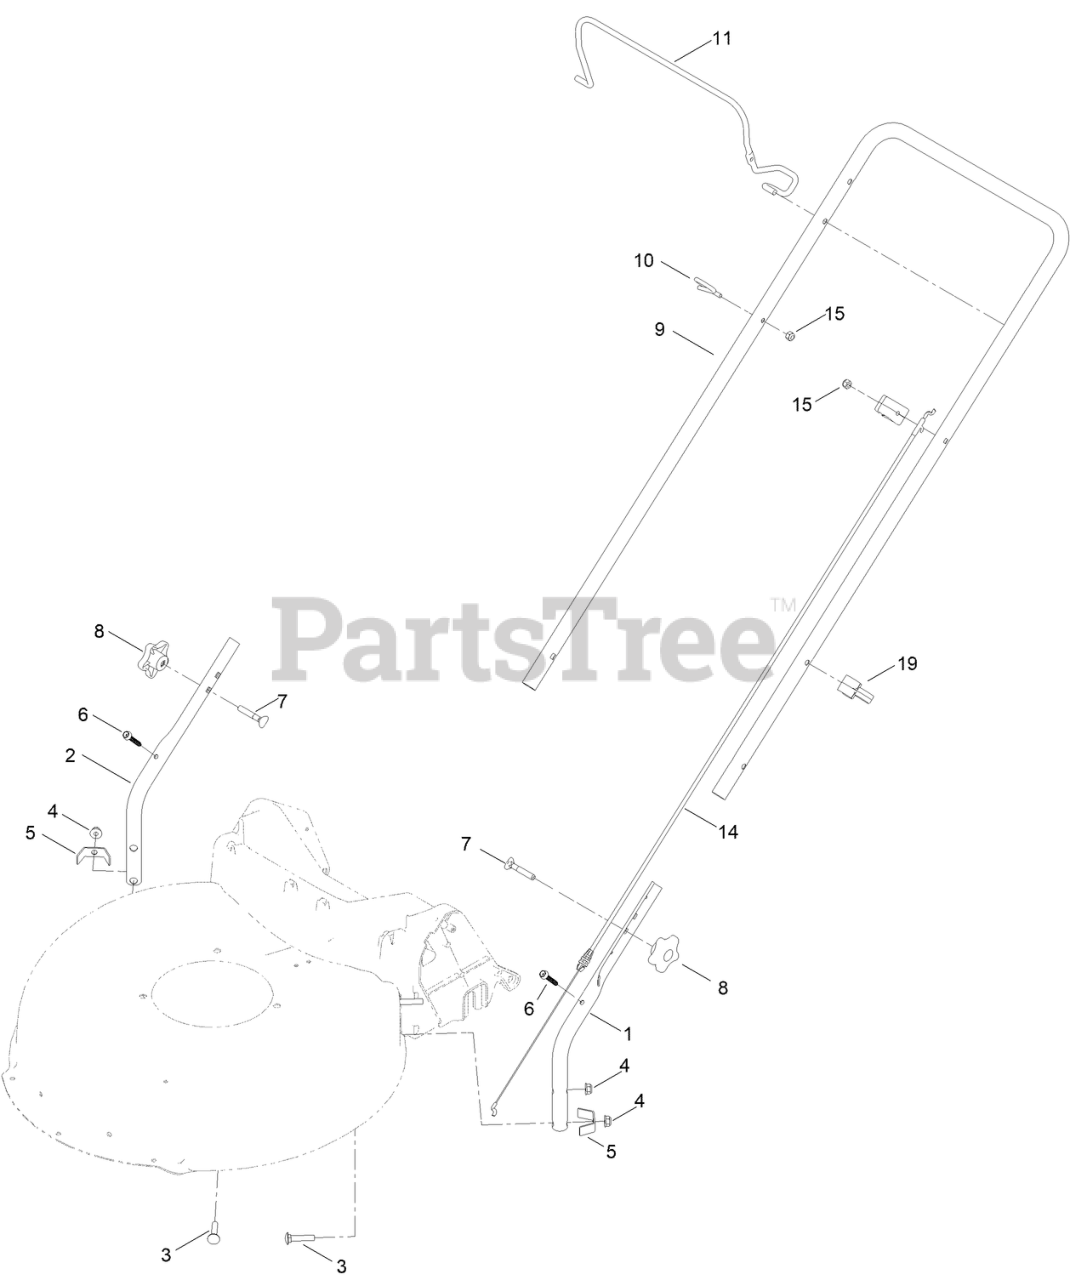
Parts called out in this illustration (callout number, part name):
1	HANDLE-LOWER, LH
2	HANDLE-LOWER, RH
3	BOLT-CARR
4	NUT-FLANGE, NI
5	BRACKET-CHUTE
6	SCREW-FLANGE, SERRATED
7	SCREW-HANDLE
8	KNOB-HANDLE
9	HANDLE-UPPER
10	GUIDE-ROPE
14	CABLE-BRAKE, ENGINE
15	NUT-LOCK, NI
19	GUIDE-CABLE
